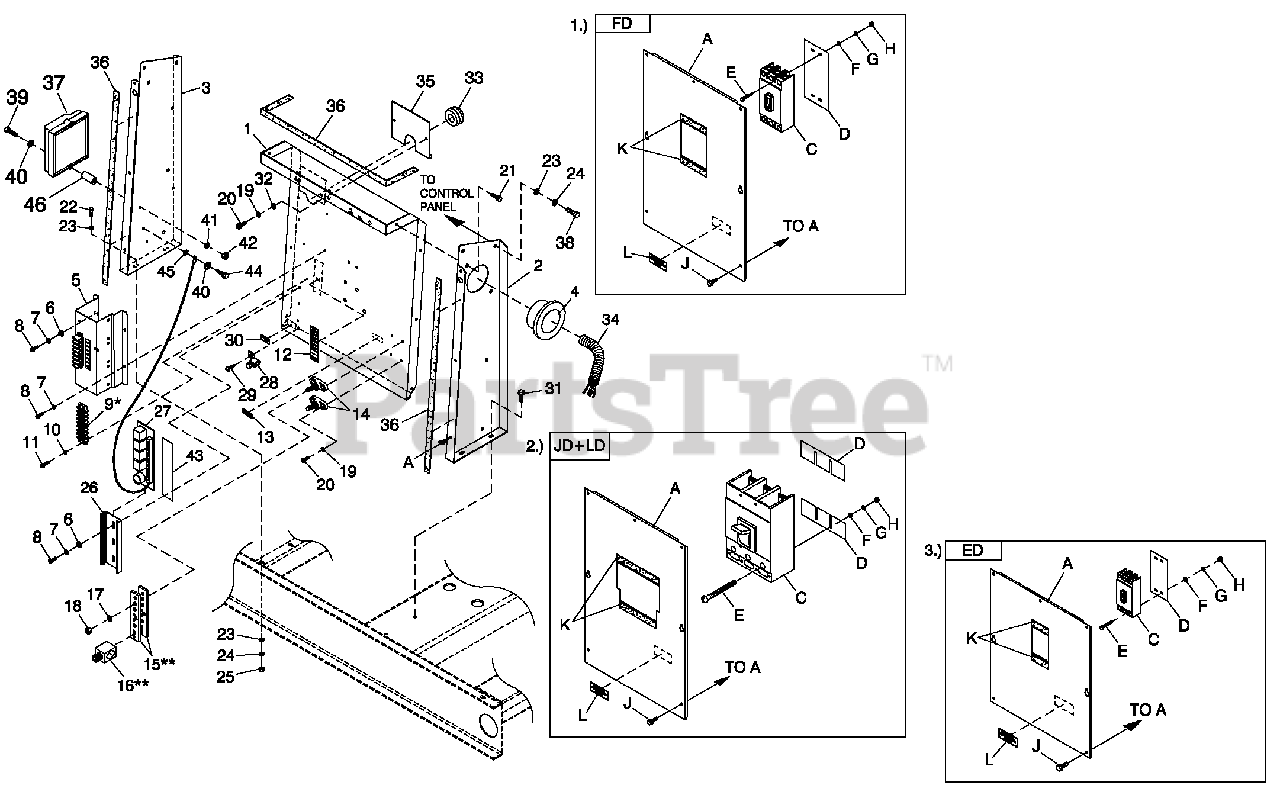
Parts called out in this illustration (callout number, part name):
1	PANEL CB CONN BOX
1	UL CIRCUIT BREAKER (FD)
2	STAND RH CONTROL
2	UL CIRCUIT BREAKER (JD+LD)
3	STAND LH CONTROL C5 GRBX
3	UL CIRCUIT BREAKER (ED)
4	BUSHING SNAP SB-2.5-31
5	INTERFACE 1PH 240V
6	WASHER FLAT M4
7	WASHER LOCK #8-M4
8	SCREW PHTTM4-0.7X 10 ZYC
9	BLOCK TERM 20A 8 X 6 X 1100V
10	WASHER LOCK#6
11	SCREW PHTT # 6-32X1 /2 ZYC
12	DECAL CPL CUST CONN H CTRL
13	DECAL NEUTRAL
14	JUNCTION BLOCK 3/8-16
15	BUS BAR NEUTRAL BLOCK 390
16	LUG SLDLSS 600/250-1/0 X 1/4-28
17	WASHER LOCK 3/8
18	NUT HEX 3/8-16 STEEL
19	WASHER LOCK M5
20	SCREW PHTT M5-0.8X 16 ZYC
21	SCREW THF M6-1 X 16 N WA Z/JS
22	SCREW HHC M6-1.0X20G8.8
23	WASHER FLAT 1/4-M6 ZINC
24	WASHER LOCK M6-1/4
25	NUT HEX M6X 1.0 G8 YEL CHR
26	RAIL SNAPTRACK PCB HOLDER BULK
27	ASSY RELAY PCB 12VDC
28	LUG SLDLSS #6-14X 13/64 CU
29	SCREW HHTT #10-32X3/8 CZ
30	DECAL GROUND LUG
31	SCREW HHTT M6-1.0X 16ZYC
32	WASHER FLAT M5
33	GROMMET 1.25 X .25 X .75
34	CONDUIT FLEX 2.0" ID
35	PLATE WIRE SNGLGALV
36	TAPE ELEC 1/2 FOAM (AS REQ'D)
37	ASSY PCB 5.4L IGN MOD PRGRMMED
38	SCREW HHC M6-1.0X 16 G8.8
39	SCREW PHM #8-32 X 2-3/4 ZINC
40	WASHER FLAT #10 ZINC
41	WASHER LOCK #10
42	NUT HEX #10-32 STEEL
43	DECAL H-100 RB3 CUST CONN
44	SCREW HHT TM4-0.7X8ZP
45	WASHER SHAKEPROOF EXT #10 STL
46	SPACER .31 X . 75 X 1 ST/ZNC
A	COVER FDFRMCB
C	CB 0150A 3P 600V S FD6 LL
D	INSULATOR CB FD FRAME 30MIL
E	SCREW SHC 1/4-20 X 4 G8.8 NZ
F	WASHER FLAT 1/4-M6 ZINC
G	WASHER LOCK M6-1/4
H	NUT HEX 1/4-20 STEEL
J	SCREW THF M6-1 X 16 N WA Z/JS
K	TAPE ELEC 1/2 FOAM (AS REQ'D)
L	DECAL CUSTOMER CONNECT INSIDE
A	COVER C IRBRKRJD/LD
C	CB 0300A 3P 600V S JD6 LL
D	INSULATOR CIRCUIT BR. JD/LD
E	SCREW RHM 1/4-20X3
A	COVER.EDCBTALL
C	CB 0090A 3P 480V S ED4 LL
D	INSULATOR CBS(ED-3P)
E	SCREW RHM #10-32X4-1/2
F	WASHER FLAT #10 ZINC
G	WASHER LOCK #10
H	NUT HEX #10-32 STEEL
